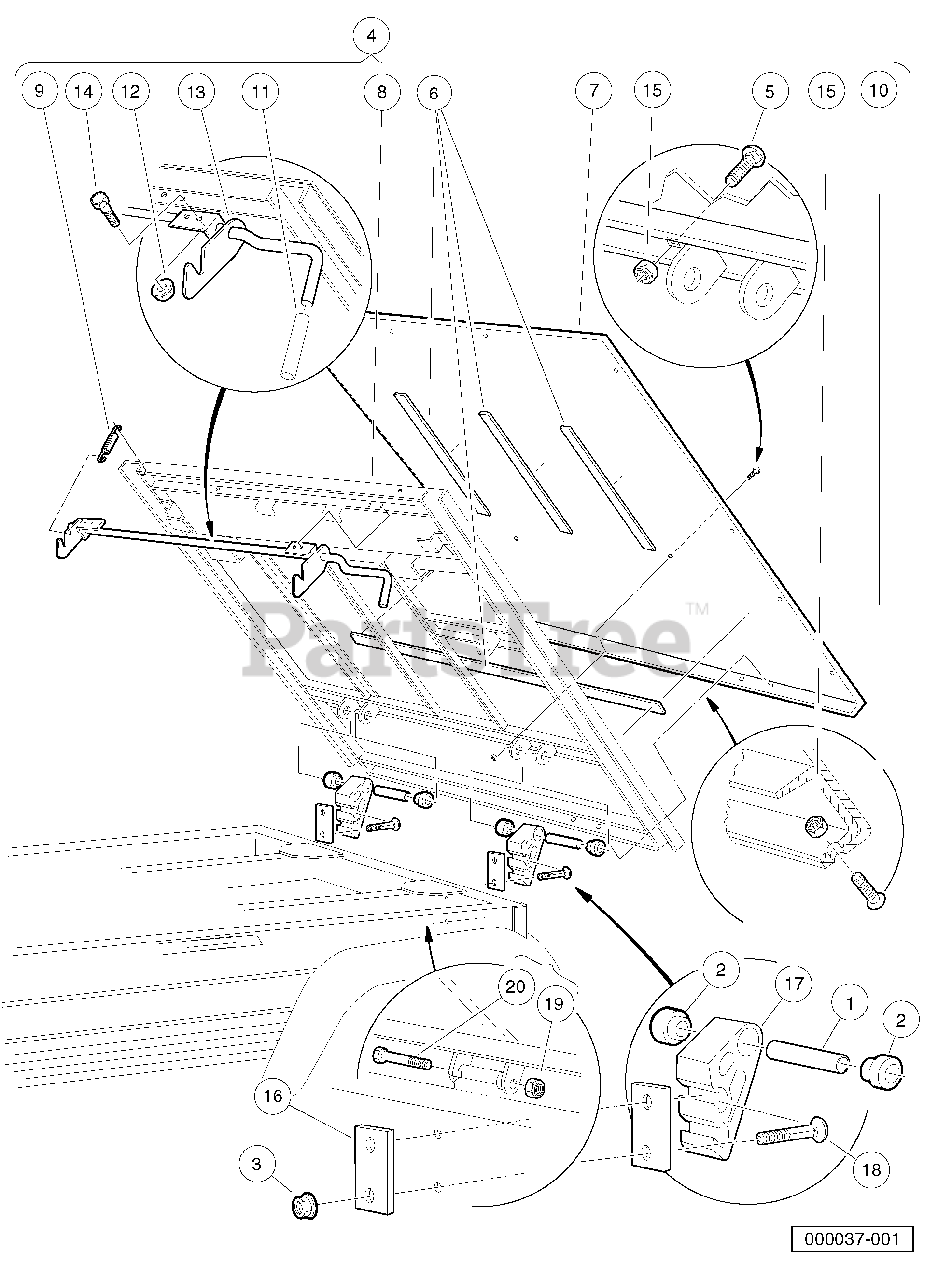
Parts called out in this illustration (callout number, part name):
1	Bushing, Steel
2	Bushing, Urethane
3	Locknut, 3/8-16 Flanged Dimple
4	Tilt Bed Assembly
5	Bolt, Carriage, 5/16-18 X 1.00
6	Tape, Vinyl Foam 1/8" x 3/4"
7	Plate, Floor Bed
8	Frame Assembly
9	Extension, Spring Latch
10	Screw, 5/16-18 X 0.88 Torx Truss-Head
11	Grip, Tilt Latch Hand
12	Locknut, 1/4-20 Hex Whiz
13	Ltch Weld Asm Tlt Bd
14	Screw, 1/4-20 X 0.625 Hex-Head Cap
15	Locknut, 5/16-18 Nylon Insert
16	Plate, Back
17	Extr, Brkt, Hinge, Bed
18	3/8-16 X 3.5 Carr Blt Gr5 Zn
19	Locknut, 3/8-16 Hex
20	Screw, 3/8-16 X 3.375 Hex Cap
